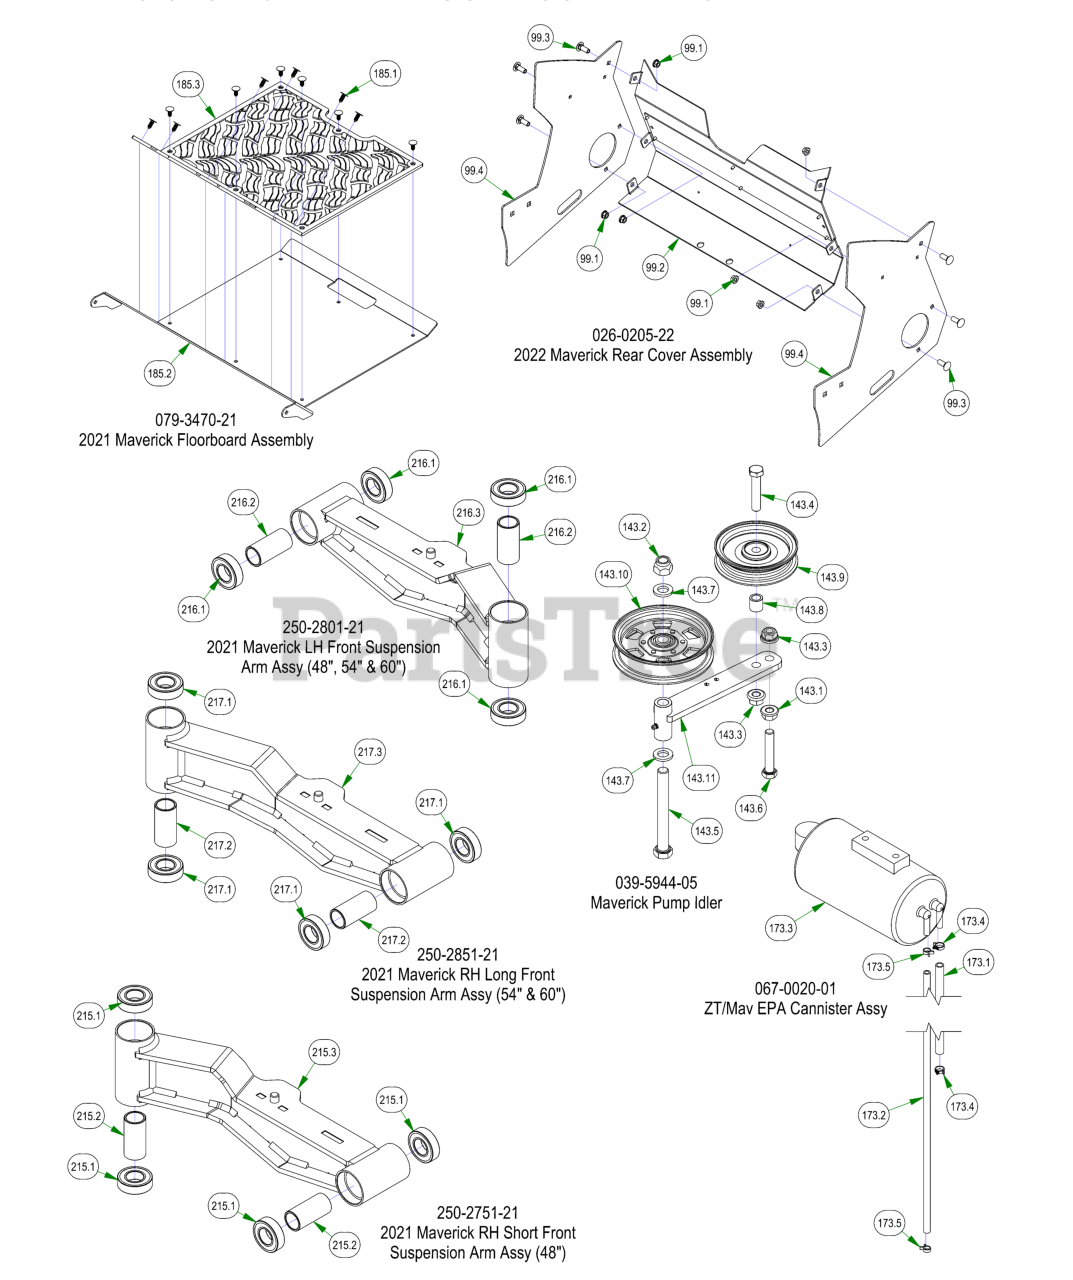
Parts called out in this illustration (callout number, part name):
99	2022 Maverick Rear Cover Assembly
99.1	5/16-18 NYLON INSERT FLANGE LOCKNUT ZINC
99.2	2021 Maverick Rear Cover Assembly
99.3	3/8-16 X 1 CARRIAGE BOLT (GR.5) ZINC
99.4	2022 Maverick Rear Cover Side Plate - Painted
143	Maverick Pump Idler
143.1	1/2-13 HEX SERRATED FLANGE NUT HARD/ZINC
143.2	5/8-11 NYLON INSERT LOCKNUT ZINC
143.3	1/2-13 NYLON INSERT FLANGE LOCKNUT ZINC
143.4	1/2-13 X 2-1/2 HEX CAP SCREW GR 5 ZINC
143.5	5/8-11 X 5-1/2 HEX CAP SCREW (GR.5) ZINC
143.6	1/2-13 X 2-3/4 HEX CAP SCREW (GR.5) ZINC
143.7	.635 ID X 1.120 OD X .140 THICK FLAT WASHER NYLON
143.8	.51 ID X .75 OD X .75 LGTH SOLID SPACER ZINC
143.9	4 3/4" Idler Pulley
143.10	5 3/4 Idler Pulley, 5/8 Bore
143.11	Deck Idler
173	ZT/Mav EPA Cannister Assy
173.1	1/4" Vinyl Tubing, 46" Long
173.2	3/16" Vinyl Tubing, 55" Long
173.3	Carbon Canister
173.4	3/16 Vinyl Clamp
173.5	3/16" Vinyl Hose Clamp
185	2021 Maverick Floorboard Assembly
185.1	Ratchet Fastener
185.2	2018 Maverick Floorboard
185.3	2021 Maverick Floor Mat W/ Reaper Tread
215	2021 Maverick RH Short Front Suspension Arm Assy (48")
215.1	1641 BEARING W/2 CONTACT RUBBER SEALS
215.2	2016 Front Bearing Spacer
215.3	2021 Maverick I-Beam Front Arm RH Short Weldment - Painted
216	2021 Maverick LH Front Suspension Arm Assy (48", 54" & 60")
216.1	1641 BEARING W/2 CONTACT RUBBER SEALS
216.2	2016 Front Bearing Spacer
216.3	2021 Maverick I-Beam Front Arm LH Weldment - Painted
217	2021 Maverick RH Long Front Suspension Arm Assy (54" & 60")
217.1	1641 BEARING W/2 CONTACT RUBBER SEALS
217.2	2016 Front Bearing Spacer
217.3	2021 Maverick I-Beam Front Arm RH Long Weldment - Painted
